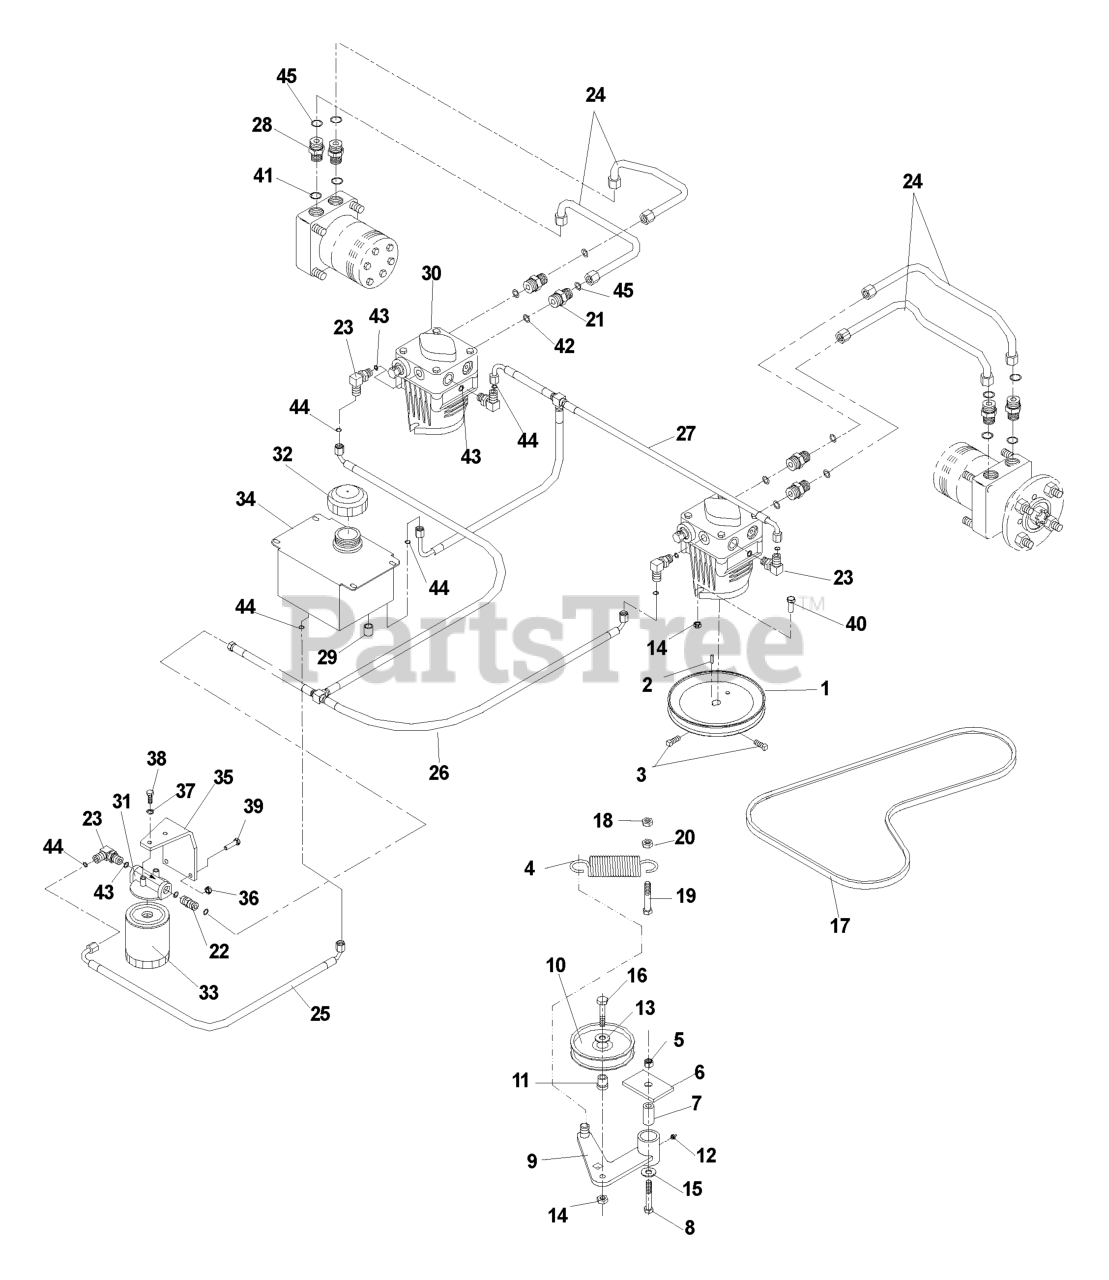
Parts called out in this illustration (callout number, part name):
2	KEY, 5MM SQ X 30MM
3	SCREW, 5/16-18 X 5/8, SET
4	SPRING, EXTENSION
5	NUT, 1/2-13, NYLOC
7	BUSHING, PIVOT
8	HCS, 1/2-13 X 3 1/4, GR5
9	IDLER ARM
10	PULLEY, IDLER
11	BUSHING, FLANGE IDLER
12	ZERK, STRAIGHT, 1/4-28
13	WASHER, 3/8
14	NUT, 3/8-16, CENTERLOCK
15	WASHER, 9/16
16	HCS, 3/8-16 X 1 3/4, GR5
17	PUMP BELT
18	NUT, 3/8-16, NYLOC
19	HCS, 3/8-16 X 2, GR5
20	NUT, 3/8-16, WHIZLK
21	FITTING, F6400-8-8-0
22	HYDRAULIC FITTING
23	FITTING, F6801-6-6-0
24	HYDRAULIC LINE
26	"T" ASSEMBLY
27	"T" ASSEMBLY
28	STRAIGHT FITTING
30	10CC PUMP W/RTN'S
31	FILTER HEAD
32	CAP-HYDRO RESERVIOR
33	FILTER ELEMENT
35	OIL FILTER BRACKET
36	NUT, 1/4-20, NYLOC
37	LOCKWASHER, 1/4
38	HCS, 1/4-20 X 5/8, GR5
39	HCS, 1/4-20 X 3/4, GR5
40	HCS, 3/8-16 X 1, GR5, WHIZLK
41	"O" RING, 3/4
42	"O" RING, 1/2
43	"O" RING, 3/8
44	"O" RING FLARE, 3/8
45	"O" RING FLARE, 1/2
